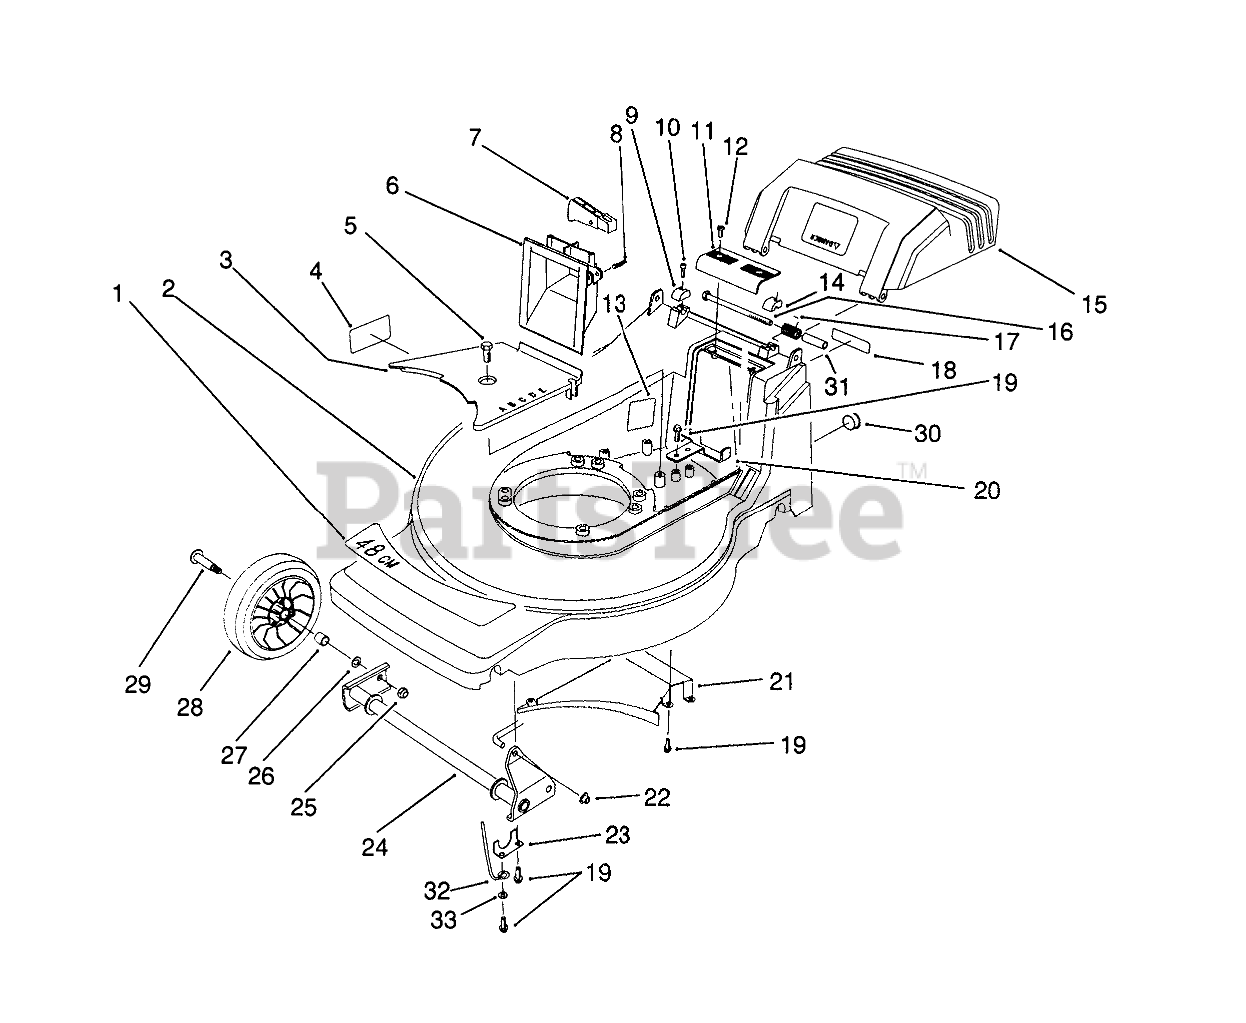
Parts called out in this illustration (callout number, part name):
1	DECAL - DECK
2	Housing-48cm (Incl. Ref. #1, 4, & 13)
3	BELT COVER
4	Decal Danger
5	SCREW-HWHTF
6	GRIP - LOWER
7	TRIGGER - HOC
8	PIN-SPIRAL
9	CAP-HINGE BOLT, RH
10	SCREW-HSH
11	GRIP-UPPER
12	SCREW-PPH, PLASTITE
13	Decal-Noise
14	CAP-HINGE BOLT, LH
15	Door-Discharge
16	SCREW-HH
17	DOOR SPRING
18	DECAL FRENCH REGUL.
19	SCREW-HWHTF
20	REAR BELT GUIDE
21	Ramp-Discharge
22	NUT-PUSH
23	FRONT SECURING PLATE
24	FRONT PIVOT WA
25	Nut
26	WASHER
27	BUSHING
28	Wheel & Tire Assembly (Incl. Ref. #27)
29	BOLT-WHEEL
30	DOME PLUG (DP-1000)
31	SPACER-DOOR
32	LH AXLE RETAINER
33	WASHER-FLAT
